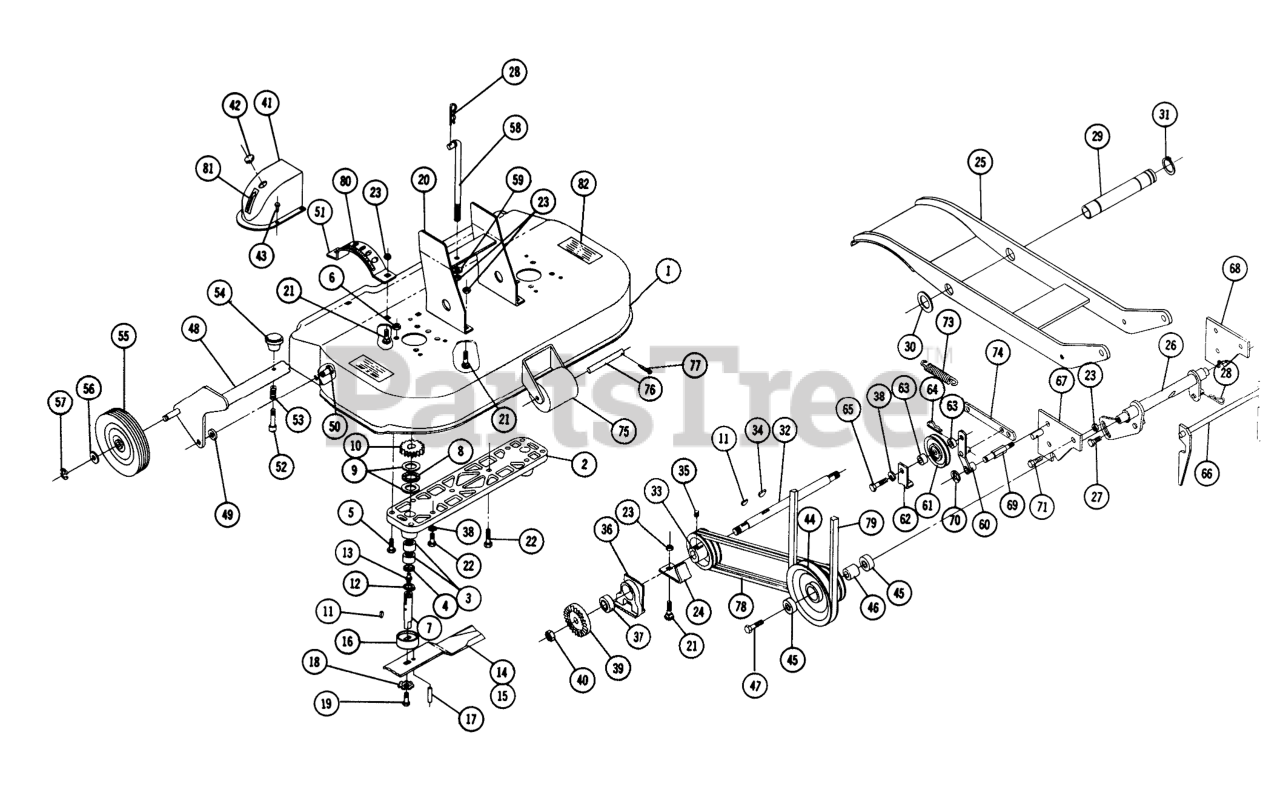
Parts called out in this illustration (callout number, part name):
1	Ass-y Deck
2	Housing
3	NEEDLE BEARING
4	Seal
5	Bolt 5/16-18 x 11/4
6	Nut 5/16-18
7	Spindle
8	Bearing Thrust
9	WASHER-THRUST
10	SPUR GEAR
11	WOODRUFF KEY
12	RING-SNAP, EXTERNAL
13	Zerk
14	Blade R.H. 18"
15	Blade L.H. 18"
16	SPINDLE CUP
17	SPIROL ROLL PIN
18	WASHER
19	Bolt 3/8-16 x 7/8
20	Ass-y Bracket-Hanger
21	Bolt-3/8-16 x 3/4
22	Bolt 3/8-16 x 1
23	3/8-16 E.S.
24	Guard
25	Ass-y-Drag Link
26	ASSY HITCH SHAFT R
27	Bolt Whizlock 3/8-16 x 5/8
28	Hairpin
29	PIVOT TUBE
30	Washer
31	SNAP RING
32	SHAFT
33	PULLEY
34	Key
35	Set Screw
36	BEARING SUPPORT
37	Ball
38	Lockwasher
39	Gear
40	Nut 5/18 Elastic Stop
41	COVER GEAR
42	PLUG BUTTON
43	SCREW
44	Pulley 3 Groove
45	BALL BEARING
46	Spacer
47	Bolt Hex 7/16-14 x 3
48	Ass-y Support-Wheel
49	WASHER
50	Bolt-Special
51	QUADRANT R
52	PLUNGER
53	Spring
54	KNOB
55	WHEEL ASSY
56	SHIM-WASHER
57	E Ring
58	LIFT ROD R
59	Washer
60	Ass-y Idler Arm
61	Pulley
62	BRACKET GUARD
63	BUSHING
64	Hairpin
65	Bolt 3/8-16 x 1
66	Ass-y Latch & Shaft
67	Ass-y Plate Pin R.H.
68	PLATE-MTG BRKT LH R (NS)
69	Support Idler
70	"E" Ring
71	Bolt 3/8-16 x 1
72	Hairpin
73	Spring
74	Link
75	Roller
76	Shaft
77	Cotter Pin
78	V-BELTS - MATCHED PR
79	V BELT
80	Decal-Height Control
81	Decal
82	Decal
